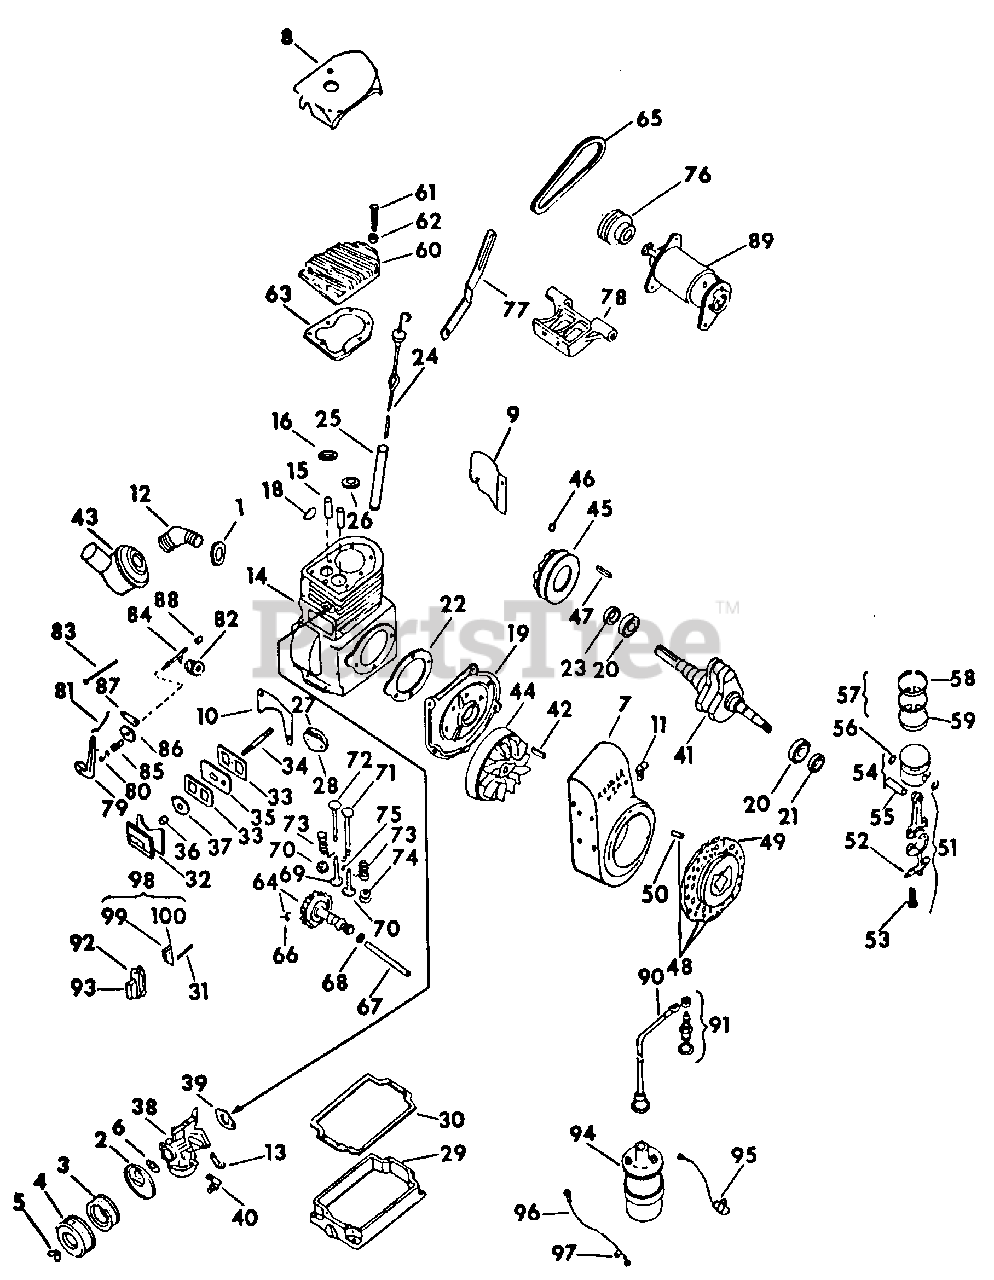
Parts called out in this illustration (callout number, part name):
1	Nut, Exhaust Muffler Elbow Lock
2	Base, Air Cleaner
3	Element, Air Cleaner Filter
4	Cover, Air Cleaner
5	Nut, Air Cleaner Wing
6	Gasket, Air Cleaner
7	Housing Assy, Blower
8	Baffle, Cylinder Head Air
9	Baffle, Cylinder Air
10	Baffle, Side Air
11	Clip, Throttle Cable
12	Elbow, Exhaust Muffler
13	Bracket, Choke
14	Block, Cylinder
15	Guide, Valve
16	Insert, Exhaust Valve
18	Plug, 1-1/8 Expansion
19	Plate, Crankcase Bearing
20	Bearing, Crankcase Ball
21	Seal, Front Bearing Plate Oil
22	Gasket, Bearing Plate
23	Seal, Crankcase Rear Oil
25	Tube, Oil Fill
26	Insert, Intake Valve
27	Gasket, Fuel Pump Pad Cover
28	Cover, Fuel Pump Pad
29	Base, Oil Pan
30	Gasket, Oil Pan Base
31	Rod, Breaker
32	Cover w/Filter, Breather
33	Gasket, Breather
34	Stud, Breather Cover
35	Plate Assy, Breather
36	Seal, Breather
37	Filter, Breather
38	Carburetor Assy
39	Gasket, Carburetor
40	Elbow, Carburetor to Fuel Line
42	Key, Crankshaft
43	Muffler, Exhaust
45	Pulley w/Clutch Drive Plate, Flywheel
46	Screw, Flywheel Pulley Set
47	Key, 1/4 X 7/8 Sq Parallel
48	Cup Assy, Flywheel Drive
49	Screen, Drive Cup Grass
50	Pin, Flywheel Drive Cup
51	Rod Assy, Connecting, Std
52	Lock, Connecting Rod Screw
53	Screw, Connecting Rod
54	Piston Assy, Std
55	Pin, Piston, .005 O/S
56	Retainer, Piston Pin
57	Ring Set, Piston, Std
58	Ring, Compression
59	Ring, Oil Control
60	Head, Cylinder
61	Screw, Cylinder Head
62	Washer, Cylinder Head
63	Gasket, Cylinder Head
64	Camshaft Assy
65	Belt, Motor Generator Drive
66	Spring, Camshaft Actuating
67	Pin, Camshaft
68	Shim, Camshaft, .005
69	Tappet, Exhaust Valve
70	Tappet, Intake Valve
71	Valve, Intake
72	Valve, Exhaust
73	Spring, Valve
74	Retainer, Valve Spring
75	Keeper, Valve Spring
76	Pulley, Motor Generator Drive
77	Brace, Motor Generator Adjusting
78	Bracket, Motor Generator Mounting
79	Lever, Governor
80	Spring, Governor
81	Linkage, Governor
82	Gear Assy, Governor
83	Pin, Governor Stop
84	Shaft Assy, Governor Cross
85	Bushing, Cross Shaft
86	Disc, Governor Regulating
87	Bracket, Speed Control
88	Bearing, Cross Shaft Needle
89	Motor Generator
90	Kit, Hi-Tension Lead
91	Plug, Spark (Champion)
92	Gasket, Breaker Cover
93	Cover, Breaker
94	Coil, Ignition
95	Condenser, Ignition Coil
96	Cable, Breaker
97	Clip, Condenser to Breaker Cable
98	Breaker & Bracket Assy
99	Bracket, Breaker Point
100	Breaker Contact Set
